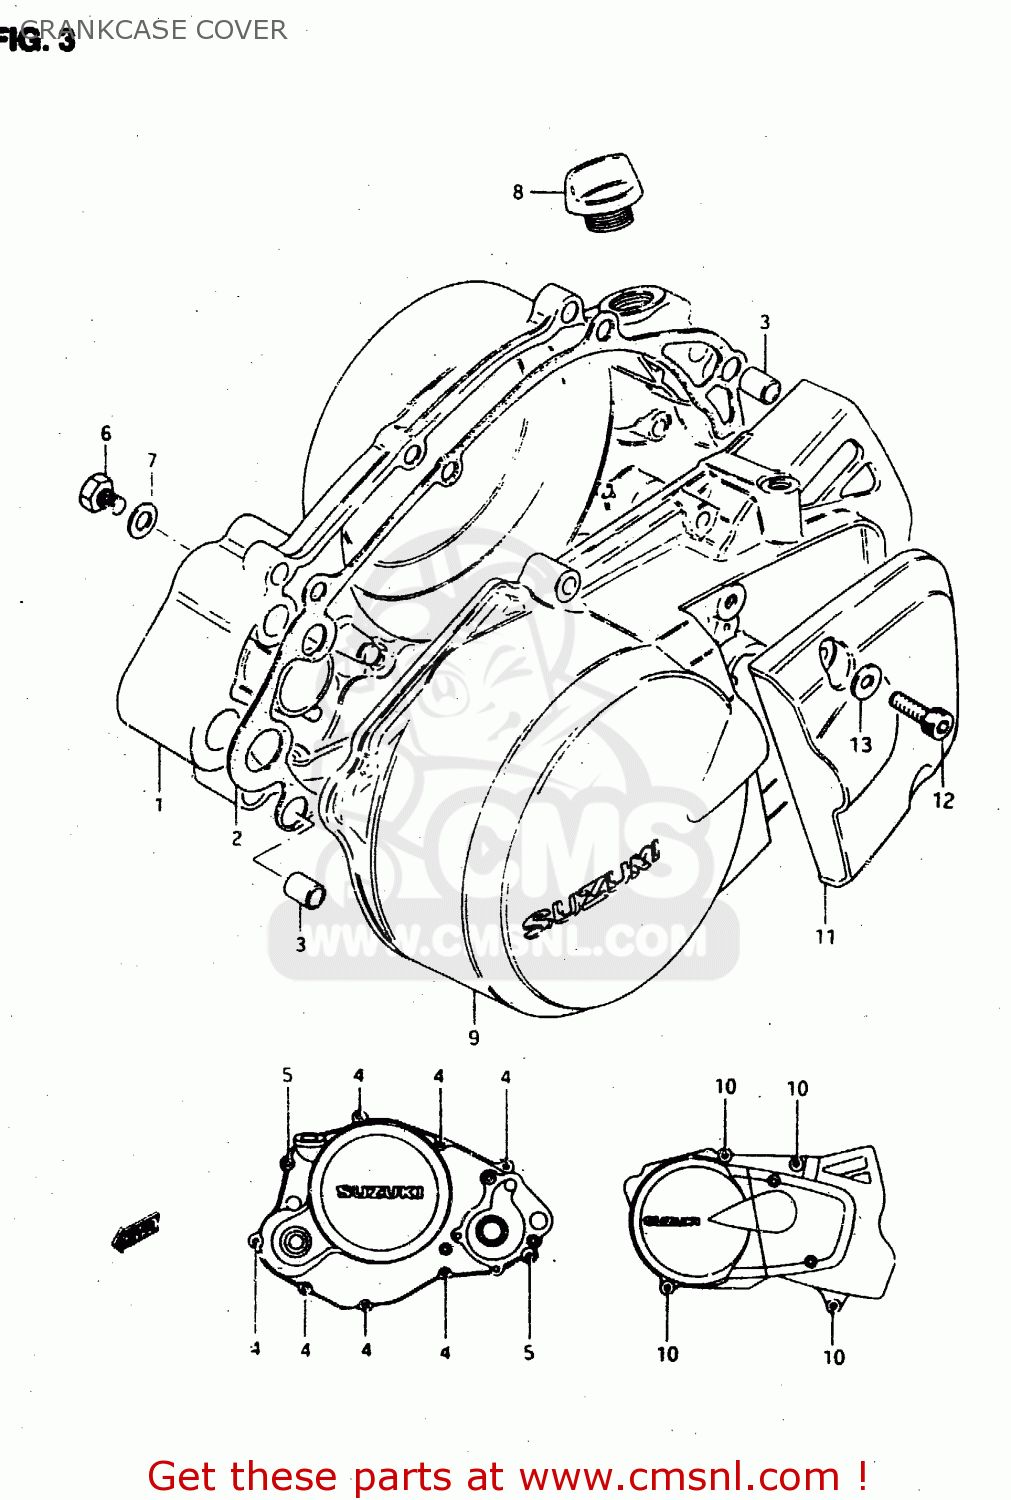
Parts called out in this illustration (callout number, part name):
1	COVER,CLUTCH
2	GASKET,CLUTCH COVER (NAS)
3	PIN
4	BOLT,CL.COVER
5	BOLT
6	SCREW(6X10)
7	GASKET(6.2X11X1) (NAS)
8	PLUG SET
9	COVER,MAGNETO
10	BOLT
11	CAP,CLUTCH RELEASE ADJUST
12	BOLT
13	WASHER
